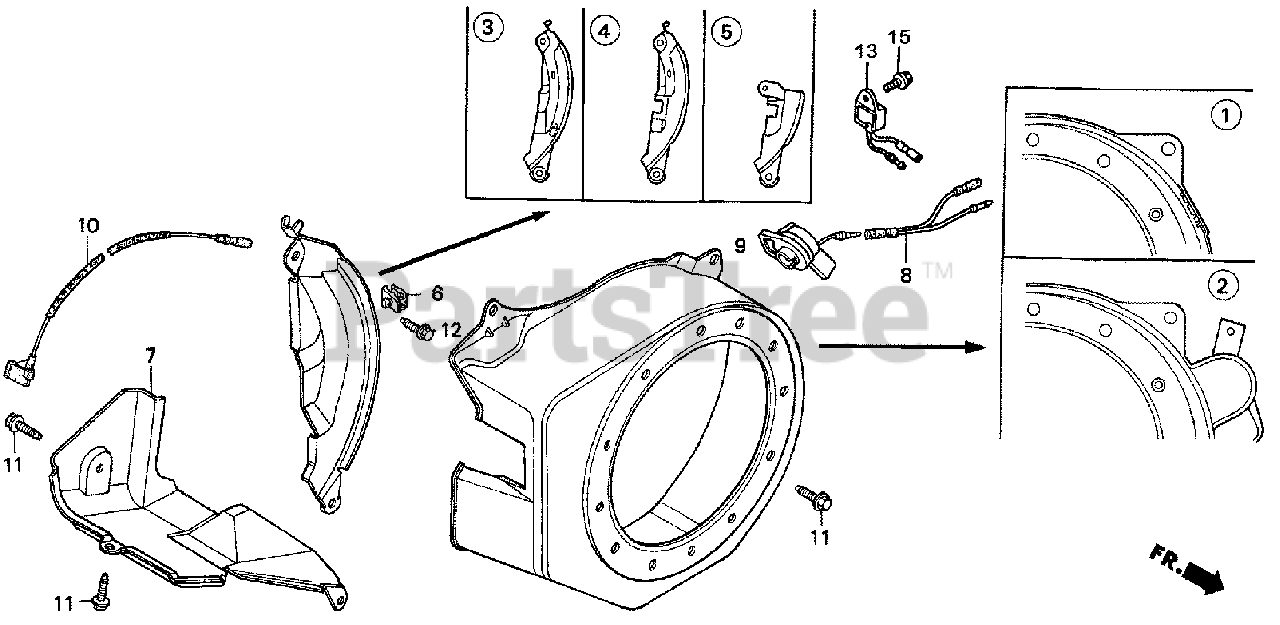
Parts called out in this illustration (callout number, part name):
1	COVER, FAN *NH246* (LOOSY GRAY)
1	COVER, FAN *R8* (BRIGHT RED)
3	PLATE, SIDE (STD)
6	CLAMP, CORD
7	SHROUD
8	SUB-HARNESS
9	SWITCH ASSY., ENGINE STOP
10	WIRE, STOP SWITCH (370MM)
11	BOLT, FLANGE (6X12) (CT200)
12	BOLT, FLANGE (6X20) (CT200)
